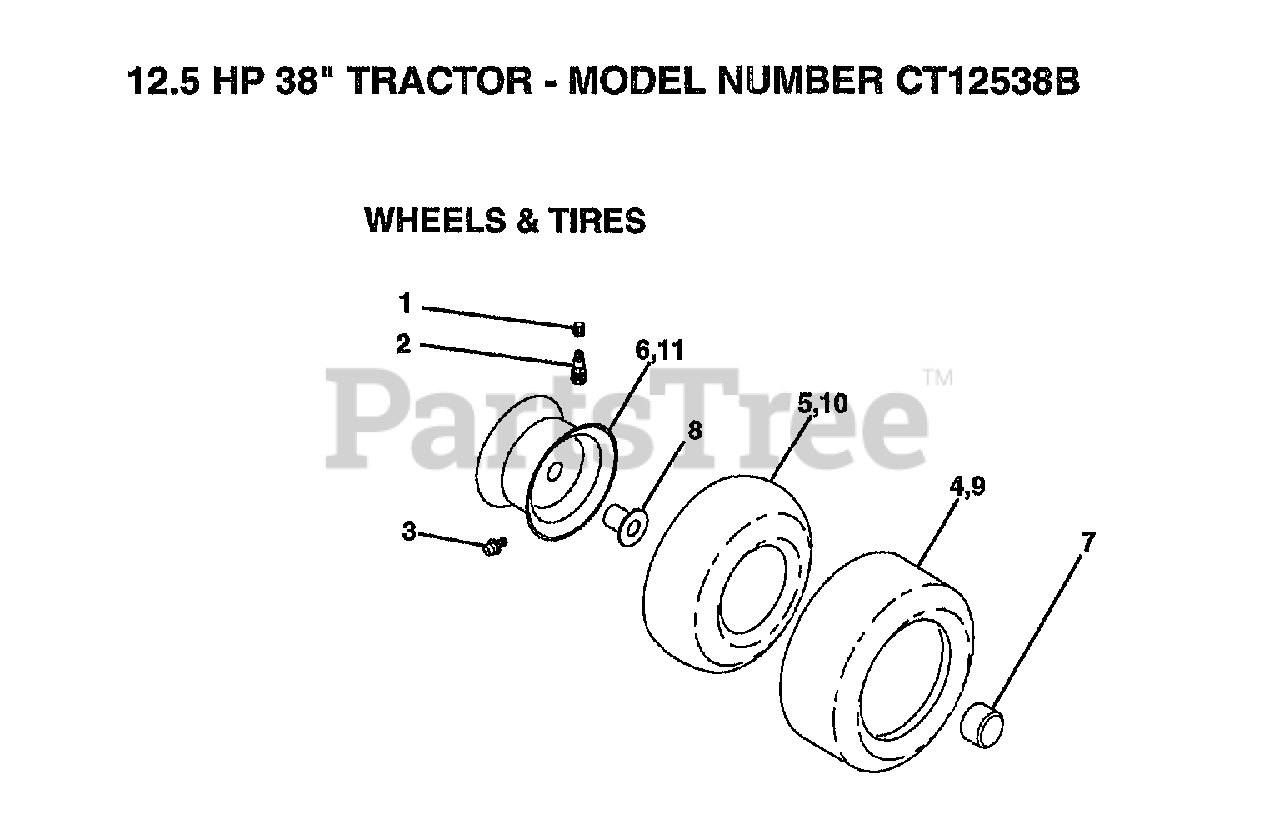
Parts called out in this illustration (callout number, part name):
1	VALVE CAP
2	VALVE STEM LT
3	FITTING LT
5	TUBE.5.3/4.5/6
7	HUB CAP
8	"FLANGE, BEARING"
10	TUBE.18X9.5-8
